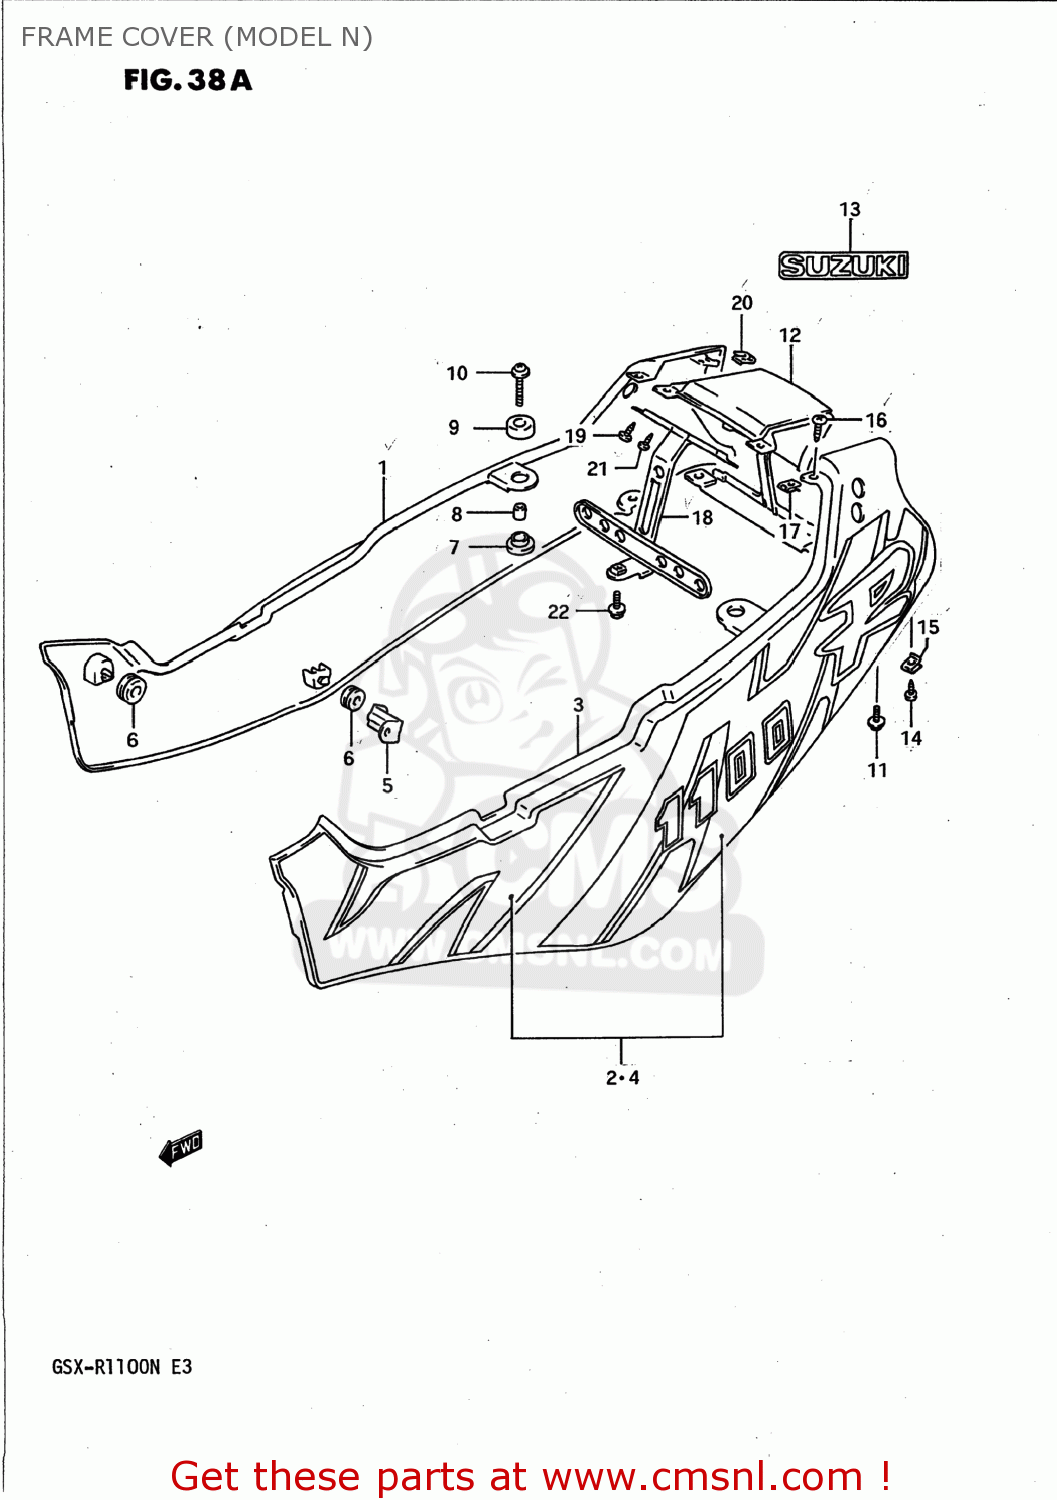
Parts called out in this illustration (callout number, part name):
1	COVER,FRAME,R(WHITE)
2	TAPE SET,FRAME COVER,RIGHT
3	COVER,FRAME,L(WHITE)
4	TAPE SET,FRAME COVER,LEFT
5	BRACKET,FRAME COVER
6	CUSHION
7	CUSHION,FRAME COVER LWR
8	SPACER
9	CUSHION,TAIL COVER UPR
10	SCREW(6X30)
11	SCREW (6X16)
12	COVER,FRAME CTR
13	EMBLEM
14	SCREW
15	NUT
16	SCREW, BRACKET
17	NUT
18	BRACKET,TAIL LAMP
19	SCREW, BRACKET
20	NUT
21	SCREW
22	BOLT
